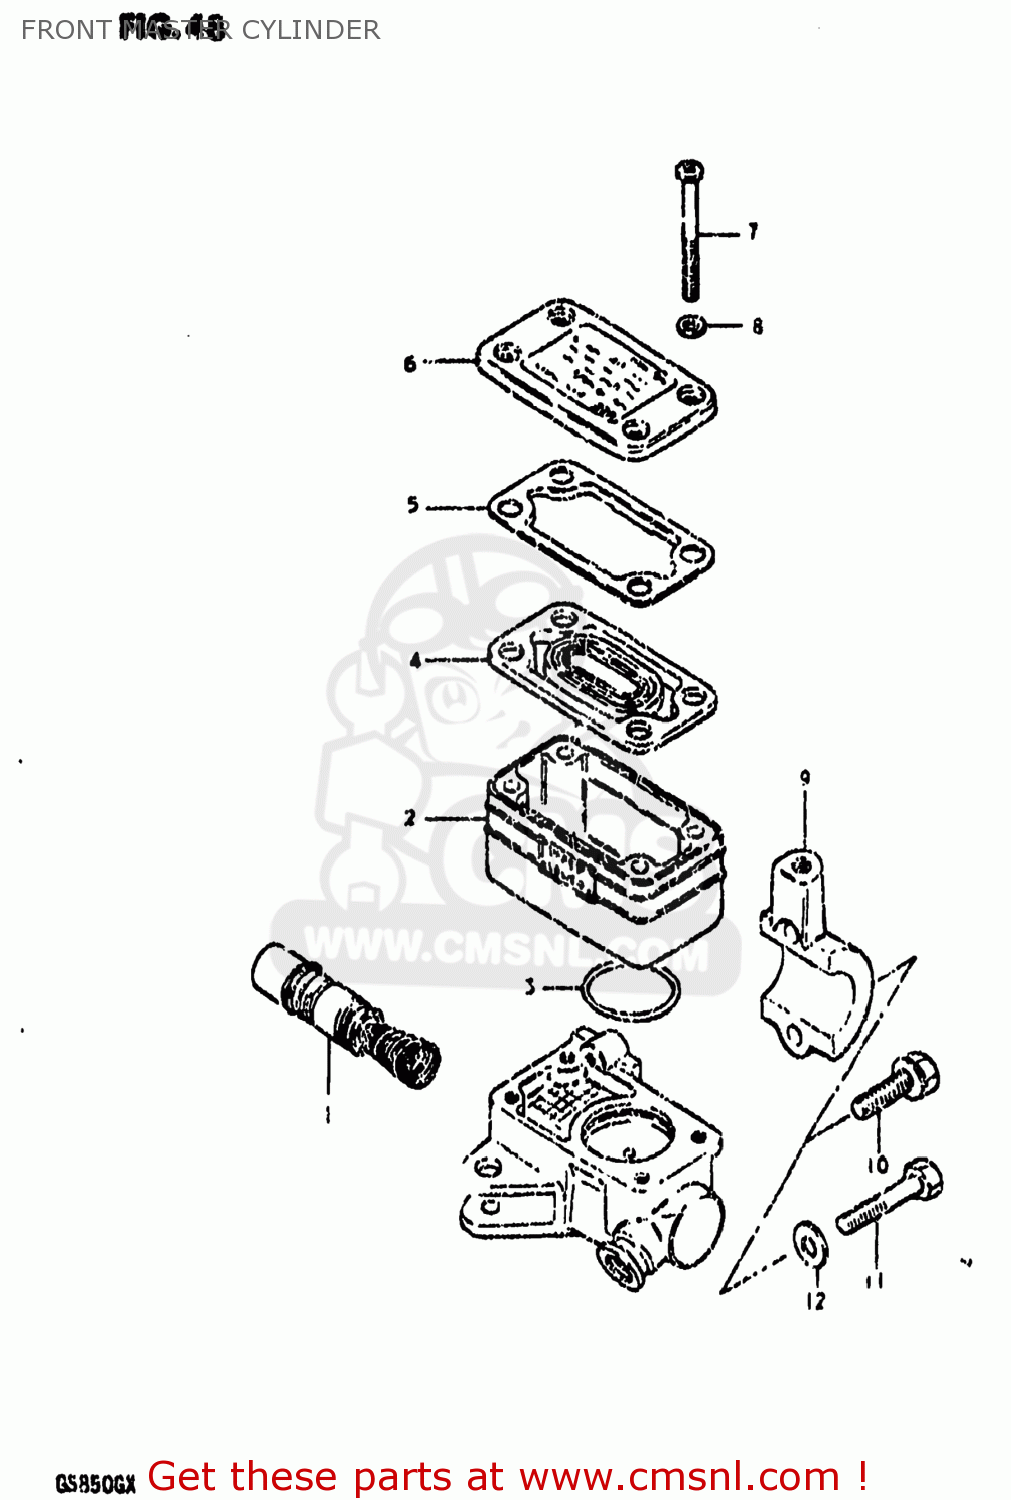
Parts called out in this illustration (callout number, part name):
0	CYLINDER ASSY,BRAKE MASTER FR
1	PISTON & CUP SET
2	RESERVOIR
3	O RING
4	RESERVOIR
5	PLATE,DIAPHRAGM
6	CAP
7	SCREW
8	WASHER
9	HOLDER
10	BOLT,MASTER CYLINDER H
11	BOLT
12	WASHER
